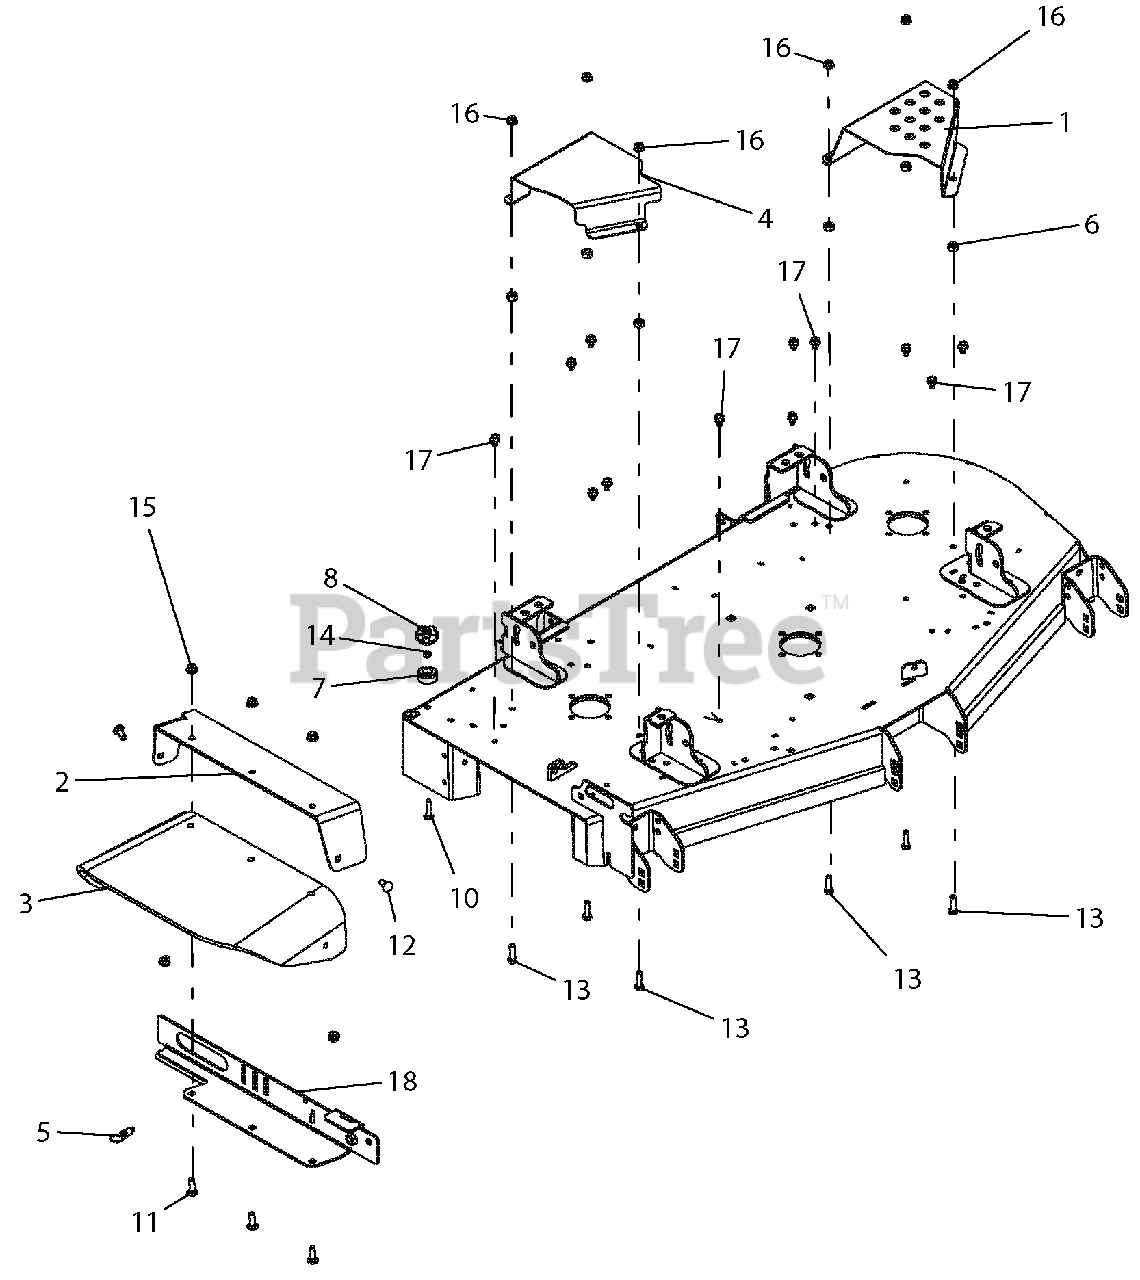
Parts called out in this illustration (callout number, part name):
1	GUARD, 44-52" LH DECK BELT-BLACK
2	DISCHARGE CHUTE SUPPORT W/SAFETY DECAL-RED
3	CHUTE, RUBBER DISCHARGE
4	GUARD, 48"-52" RH DECK BELT-BLACK
5	PULL PIN,.50-13THDX.310 PLNGR
6	NUT-HEAVY HEX .38-16 YWZC
7	BUMPER, RECESSED 1.50 X .63 W/.31 HOLE
8	KNOB, CLAMPING
10	BLT-RDHDSQNK .31-18X1.50 G5 YWZC
11	BLT-RDHDSQNK .38-16X1.25 G5 YWZC
12	BLT-RDHDSQNK .38-16X1.00 G5 YWZC
13	BLT-HEX .38-16X1.25 GR5 YWZC
14	NUT-LK-CTR .31-18 YWZC
15	NUT-LK-NYL-FLG .38-16 YWZC
16	@NUT-SPNLK-FLG .375-16 YWZC
17	SCR-TAP .38-16X.50 HWH TR YWZ
18	WLDMT, 52"-60" DISCH CHUTE MTG-RED
